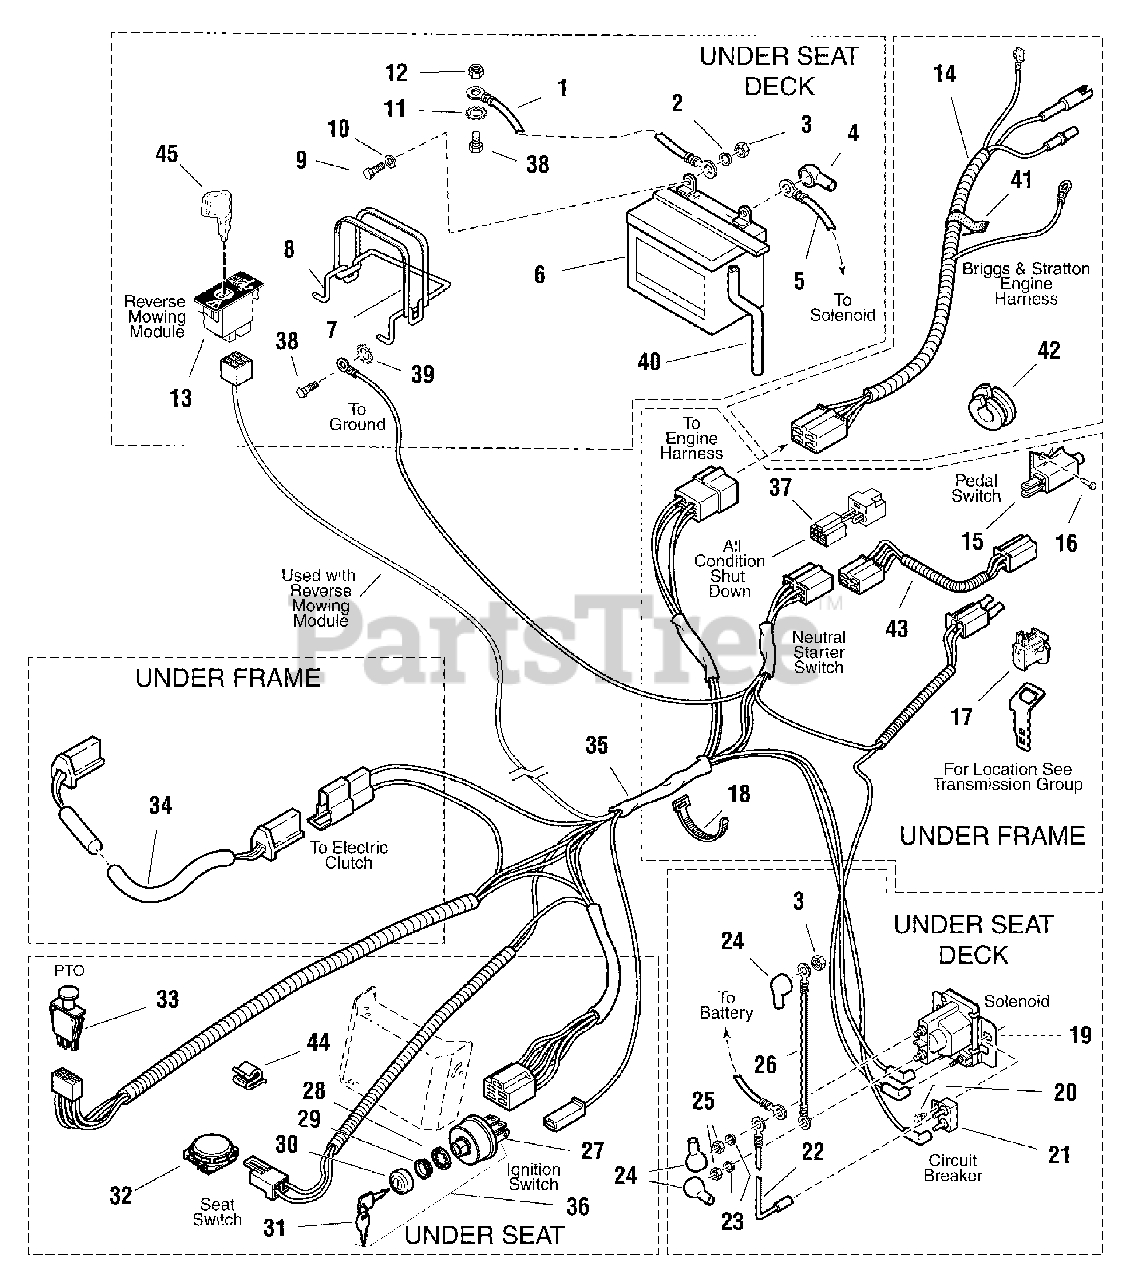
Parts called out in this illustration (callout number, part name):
1	CABLE, Battery to Ground
2	WASHER, Lock, 1/4
3	NUT, Hex 1/4-20
4	BOOT, Insulator
5	CABLE, Battery to Solenoid (Briggs & Stratton Models)
5	CABLE, Battery to Solenoid (Kohler Models)
7	STRAP, Battery
8	BRACE, Battery
9	CAPSCREW, Hex Head, 1/4-20 x 3/4
10	WASHER
11	WASHER, Lock, External Tooth, 3/8
12	NUT, Hex, 3/8-16
13	MODULE, Reverse Mowing
14	WIRE ASSEMBLY, Harness to Engine (Briggs & Stratton Only)
15	SWITCH, Neutral Start
16	POP-RIVET
17	SWITCH, Push Button (N.O.)
18	TIE, Self-Locking
19	SOLENOID
20	CAPSCREW, Hex Head, Taptite, 1/4-20 x 1/2
21	CIRCUIT BREAKER
22	WIRE ASSEMBLY
23	LOCKWASHER, 5/16 Yellow
24	COVER, Terminal
25	NUT, Hex, 5/16-24
26	CABLE, Solenoid to Starter
27	SWITCH, Ignition (6 pole)
28	WASHER, Internal Tooth, 5/8
29	NUT
30	COVER, Keyswitch
31	KEYS (Set of 2 Keys)
32	SWITCH, Seat, Gray Switch, Gray Retainer
32	SWITCH, Seat, Gray Switch, Black Retainer
33	SWITCH, PTO, Push/Pull
34	WIRE HARNESS, Clutch
35	HARNESS, Wiring (No Reverse Mowing Option)
35	HARNESS, Wiring (With Reverse Mowing Option)
36	IGNITION KEY SWITCH ASSEMBLY
37	WIRING ASSEMBLY, All Conditions Shutdown
38	CAPSCREW, Hex head 1/4-20 x 3/4
39	WASHER, Lock, External Tooth, 5/16
40	TUBE, Vent (Early Models Only)
41	CLAMP, Wire, 5/16 Diameter
42	GROMMET (11 HP 5-Speed Models Only)
43	WIRE ASSEMBLY, Neutral Switch (11 HP Coronet Only)
44	CLIP (14 HP Hydro Qty=1)
45	KEY, RMO Module, Plastic
